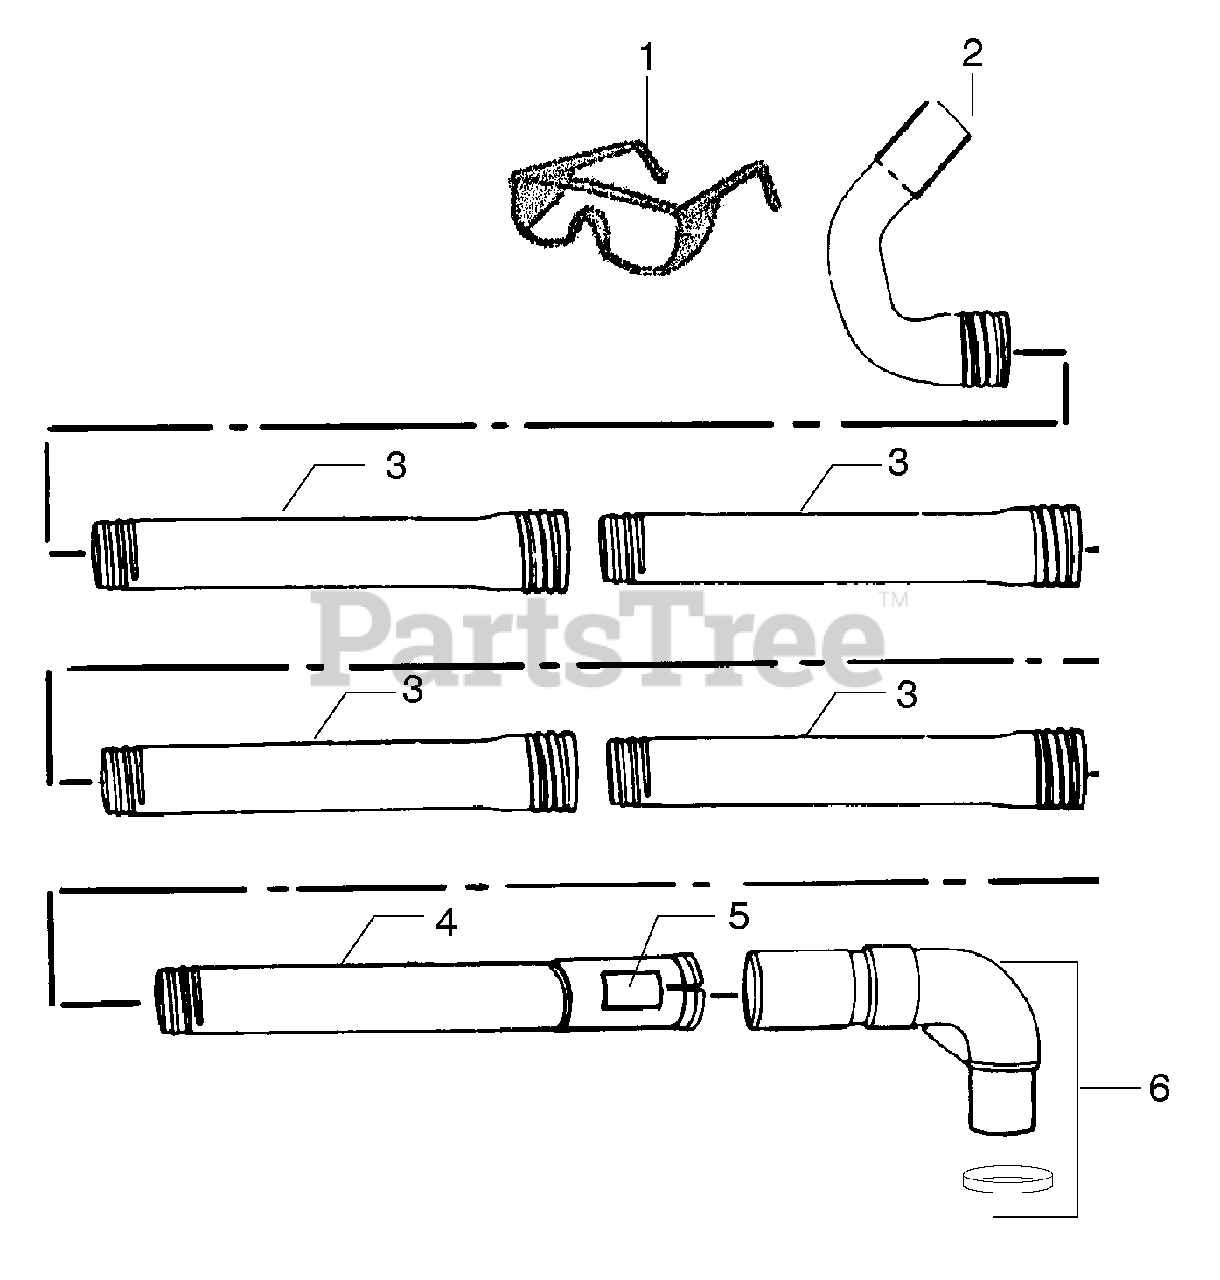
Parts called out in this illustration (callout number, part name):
1	Glasses
3	Tube-Extension
5	Decal-Warning
6	Elbow&Spacer Ring
